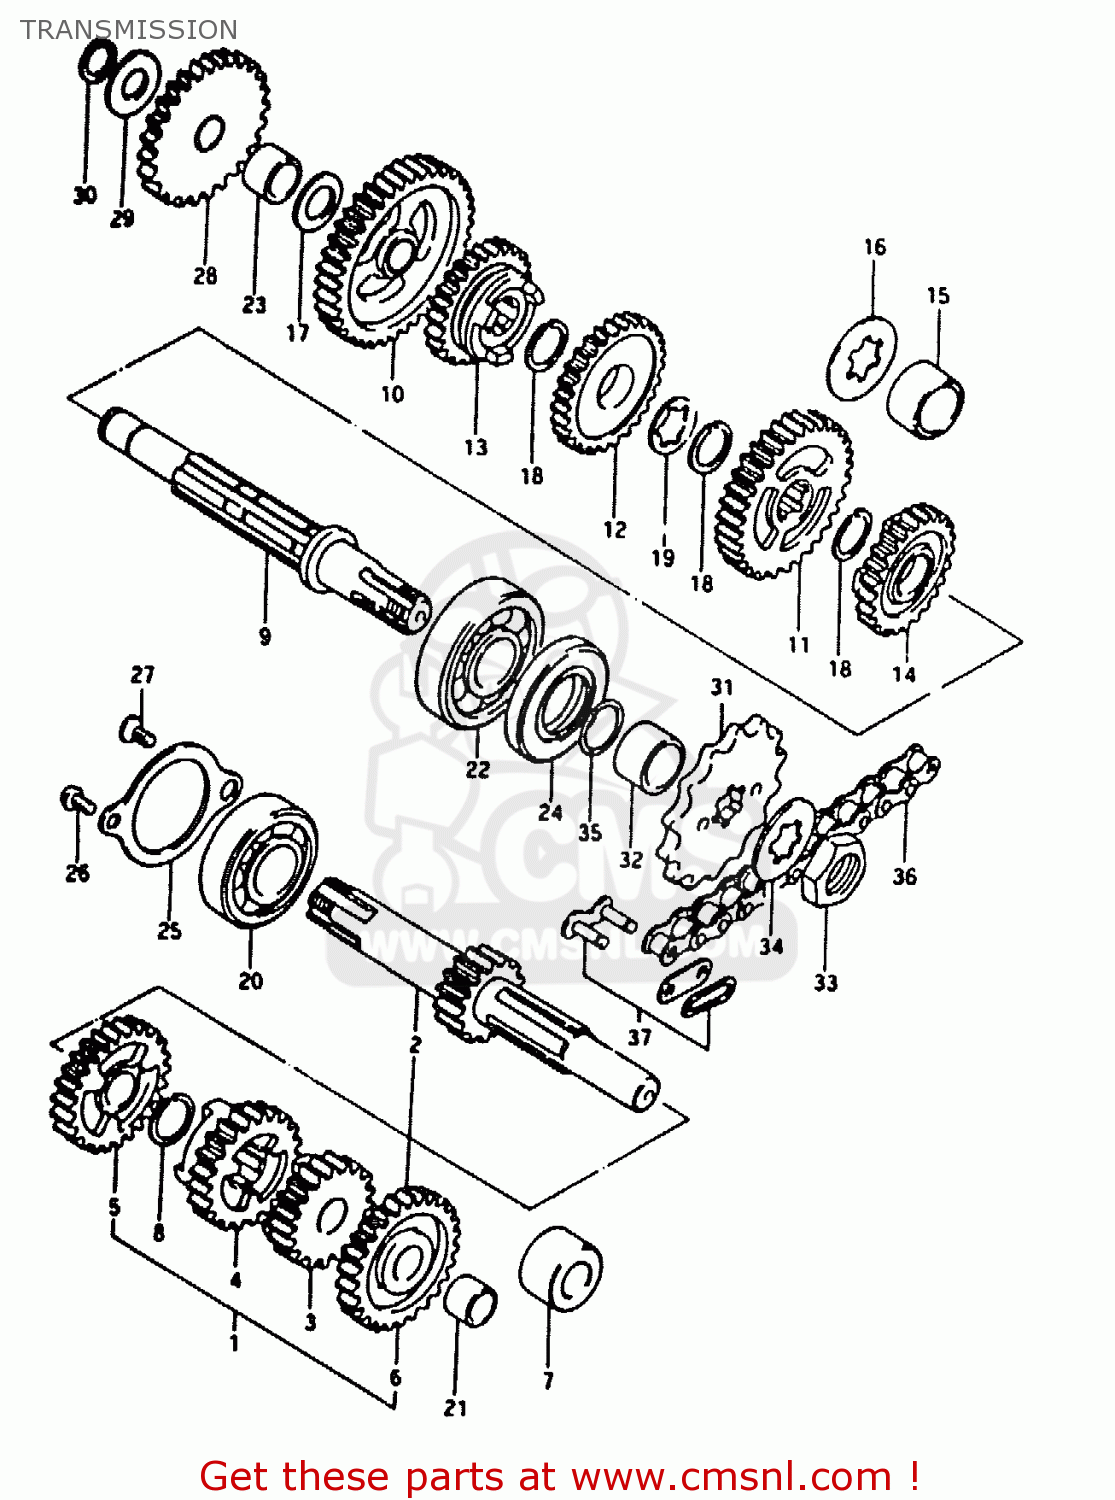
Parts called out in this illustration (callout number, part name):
1	SHAFT,COUNTER
2	SHAFT,COUNTER(NT:12)
3	GEAR,SECOND DRIVE
4	GEAR,THIRD DRIVE
5	GEAR,4TH DRIVE(NT:24)
6	GEAR,FIFTH DRIVE
8	CIRCLIP
9	SHAFT,DRIVE
10	GEAR,FIRST DRIVEN
11	GEAR,2ND DRIVEN(NT:33)
12	GEAR,3RD DRIVEN(NT:29)
13	GEAR,FOURTH DRIVEN
14	GEAR,5TH DRIVEN(NT:24)
17	WASHER(13X24X1)
18	CIRCLIP
19	WASHER,LOCK
20	BEARING
21	BUSH
22	BEARING
23	BUSH
24	SEAL,OIL(21X40X6)
25	RETAINER,CNTR SHAFT BEARING
26	SCREW
27	SCREW
28	GEAR,KICK STARTER IDLE
29	WASHER
30	CIRCLIP
31	SPROCKET,ENGINE(NT:12)
32	SPACER(17X21X13)
33	NUT
34	WASHER,LOCK
35	O RING(D:1,ID:16.8)
36	CHAIN, DRIVE (420X114L)
37	JOINT,CHAIN(RK)
